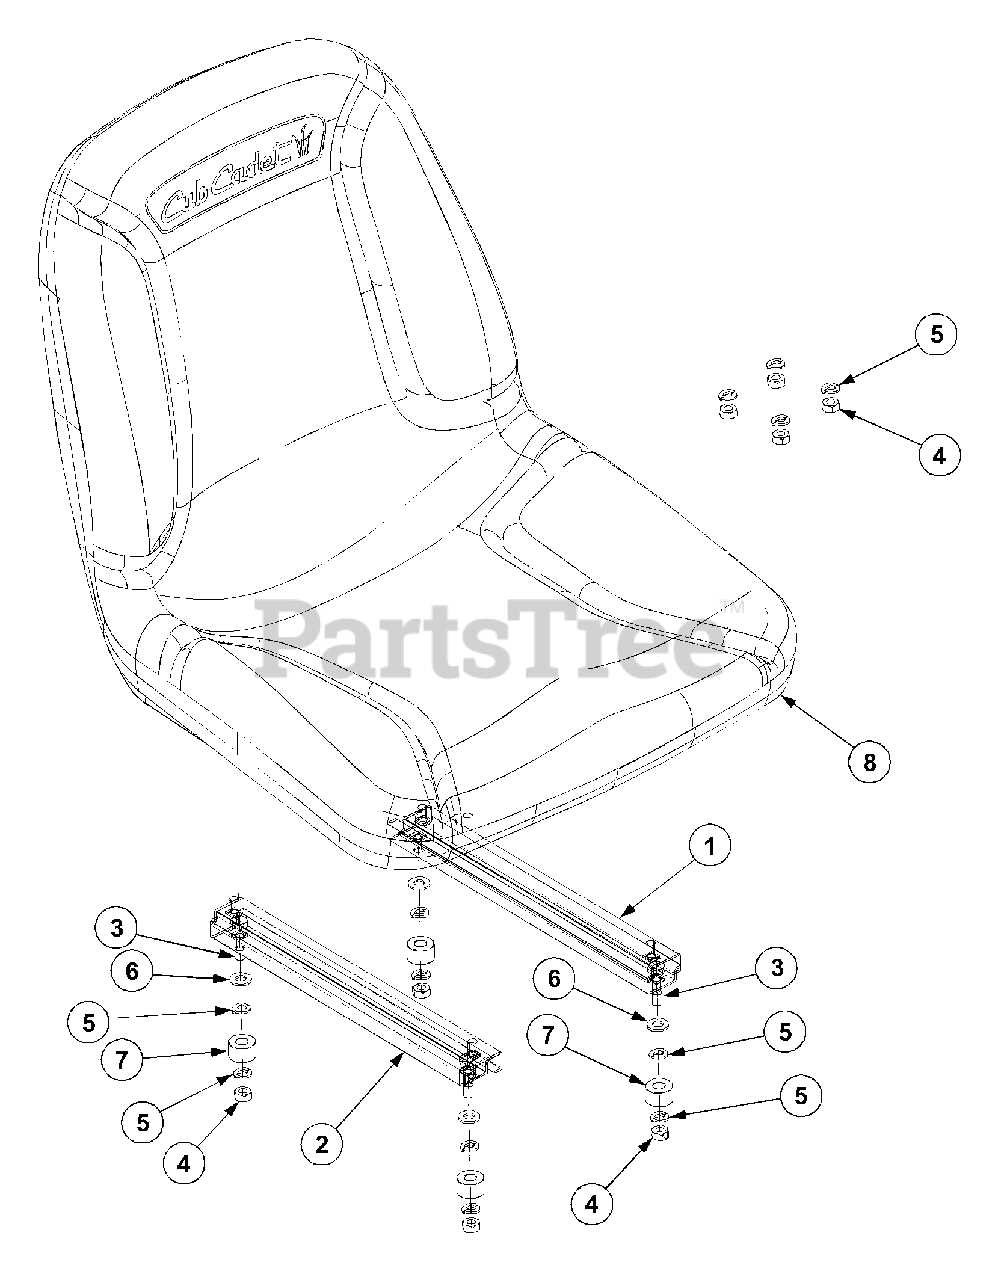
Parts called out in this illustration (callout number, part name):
1	Track, Seat Slide
2	Track. Seat Slide Adjustment
3	Screw, HHC, 5/16-18 x 1.25 GR5
4	Nut, Hex, M8 x 1.25 GR8.8
5	Washer, Lock, 5/16
6	Washer, Flat, .344 x .688 x .065
7	Spacer, .387 x .875 x .54
8	Seat
